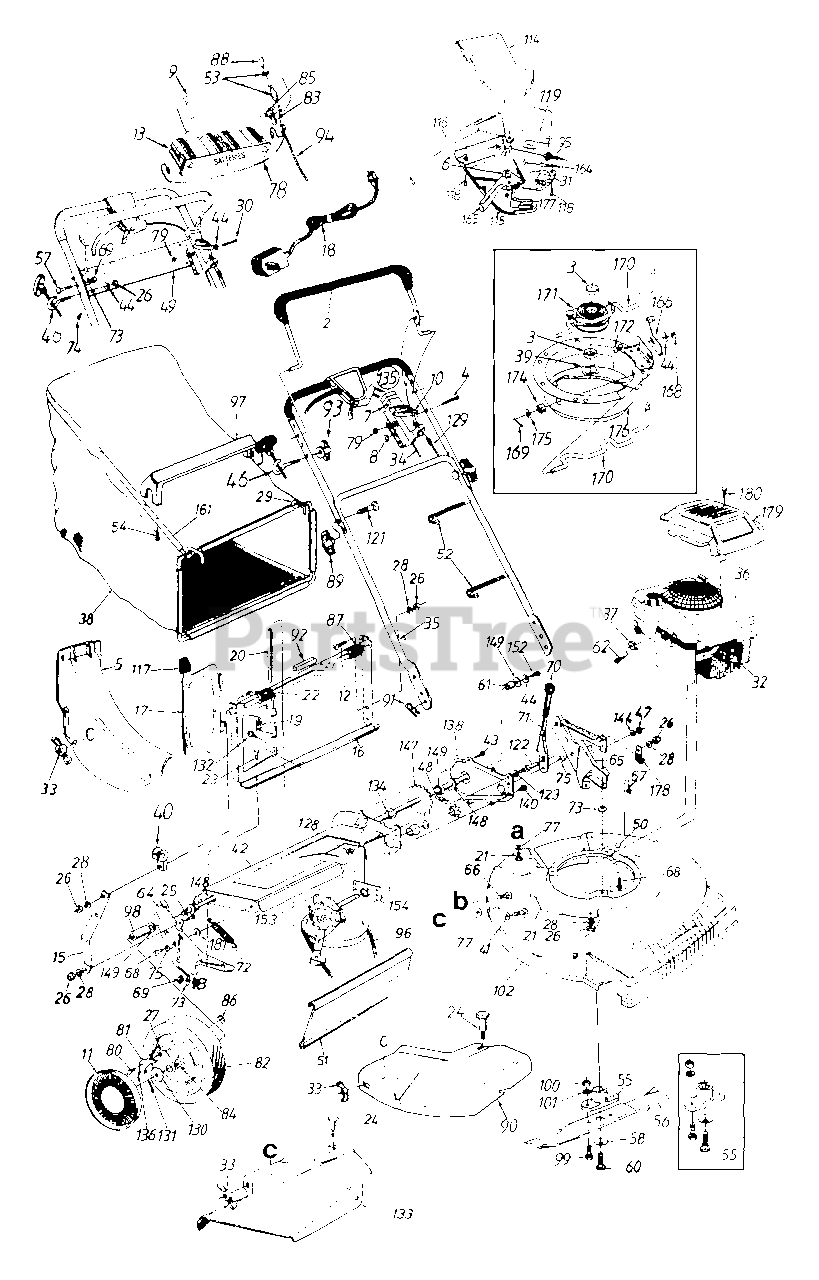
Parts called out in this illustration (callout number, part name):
2	Control Handle
3	Spacer .895" I.D. x 1" O.D.
4	Oval C-Sunk Scr.
5	Rear Discharge Chute Ass'y.
6	3 Tooth Rack Gear Insert
7	Throttle Body
8	Spr. Wash. .66" I.D.
9	Battery Tray
10	Throttle Lever
11	Hub Cap
12	Truss Mach. Scr. 1/4-20 x .62"
13	Battery Pack - 12 Volt
19	Torsion Spring
21	Carriage Bolt 1/4-20 x .62"
22	Truss Mach. Scr. 1/4-20 x .75"
23	Hex AB-Tap Scr. 1/4-20 x .38"
24	Shoulder Bolt Special
25	Hex Bolt 1/4-20 x .62" Lg.
26	Hex Nut 1/4-20 Thd.
27	Pawl Plate
28	L-Wash. 1/4" I.D.
30	Hex Bolt 1/4-20 x 2" Lg.
31	S.P. Control Cover
32	Spark Plug Insulator
33	Wing Nut
34	Throttle Cable 61"
36	Engine
37	Casing Clamp
38	Grass Bag
39	Wave Wash. .88" I.D. x 1.38" O.D.
40	Rope Guide - Lower
41	Ft-Wash. .344" I.D. x .62"
44	Bell-Wash. 1/4" I.D.
46	Rope Guide - Upper
47	Hex Patch L-Nut 3/8-24 Thd.
48	#48 Chain .500" Pitch x 30 Links
52	Cable Tie
53	Ignition Switch
54	Hex AB-Tap Scr. #12 x 1.25"
55	Blade Adapter Kit
56	21" Mulching Blade
57	Curved Carr. Bolt 5/16-18 x 1.38" Lg.
58	Bell-Wash. .39" I.D.
60	Hex Bolt 3/8-24 x 1.5"
61	Spacer .513" I.D.
62	Hex Wash. Hd. Scr. #10-32 x .62" Lg.
67	Hex B-Tap Scr. 5/16-18
68	Hex TT-Tap Scr. 3/8-16
69	Hex Nut 5/16-18 Thd.
71	Height Adj. Lever
72	Extension Spring 3.80" Lg.
73	Bell-Wash. 5/16" I.D.
74	Truss Mach. Tap Scr..75" Lg.
75	Shld. Spacer .5" Dia.
77	Bolt Retainer 1/4 x .50" O.D.
78	Wire Harness
79	Hex L-Nut 1/4-20 Thd.
80	Shld. Scr. .342" Dia. x .268
81	Pawl - R.H.
82	Wheel Ass'y. Comp.
83	Plug
84	Sleeve Bearing 1/2" I.D.
85	Fuse Holder
86	Flat Nut 1/4-20 Thd.
88	Ignition Key
89	Hand Knob
90	Mulching Plug
91	Hairpin Clip
92	Foam Strip 1/4" x 1" Lg.
93	Wing Nut 1/4-20 Thd. (899D)
94	Harness Extension
95	S.P. Cable - 50" Lg.
96	"V" - Belt
98	Sleeve .526" I.D.
99	Hex Bolt 3/8-24 x 1.0" Lg.
100	Hex Nut 3/8-24 Thd.
101	L-Wash. 3/8" I.D.
115	Self-Propelled Control Cover
116	Control Lever
117	Door Grip
118	Fl-"C"-Sunk Hd. Tap Scr. #10 x .75" Lg.
119	6-Speed Rack Cable Brkt.
121	Curved Hd. Bolt 5/16-18 x 2" Lg.
122	Shld. Pin 1.43" Lg.
123	L-Wash. 3/8" I.D.
128	Hex Jam Nut 3/8-24 Thd.
129	Control Cable - 44"
130	Ratchet Wheel 1.62" O.D.
131	Cotter Pin 1/8" Dia. x 1"
132	Hex B-Tap Scr. #10 x .38" Lg.
133	Side Chute Deflector Ass'y.
134	Hex Flange Bearing
135	Throttle Box Comp.
136	Spring - Nylon
144	Fl-Wash. .385" I.D. x .87"
147	Rear Shaft Ass'y. 21.94" Lg.
148	Hex Flange Brg. .506" I.D.
149	Fl-Wash. .531" I.D. x .930"
152	Hex Bolt 1/4-20 x .62" Lg. (Grade 5)
153	Transmission Comp.
164	Spd. Control Cable - 50" Lg.
165	6-Spd. Shift Lever
169	Cot-Pin 3/32" Dia. x .75" Lg.
171	Pulley Ass'y.
172	Carr. Bolt 1/4-20 x .5" Lg.
174	Flanged Bushing
175	Fl-Wash. .328" I.D. x .68" O.D.
180	Screw #10 x 1.25" Lg.
181	Fl-Wash. .383" I.D. x 1" O.D.
